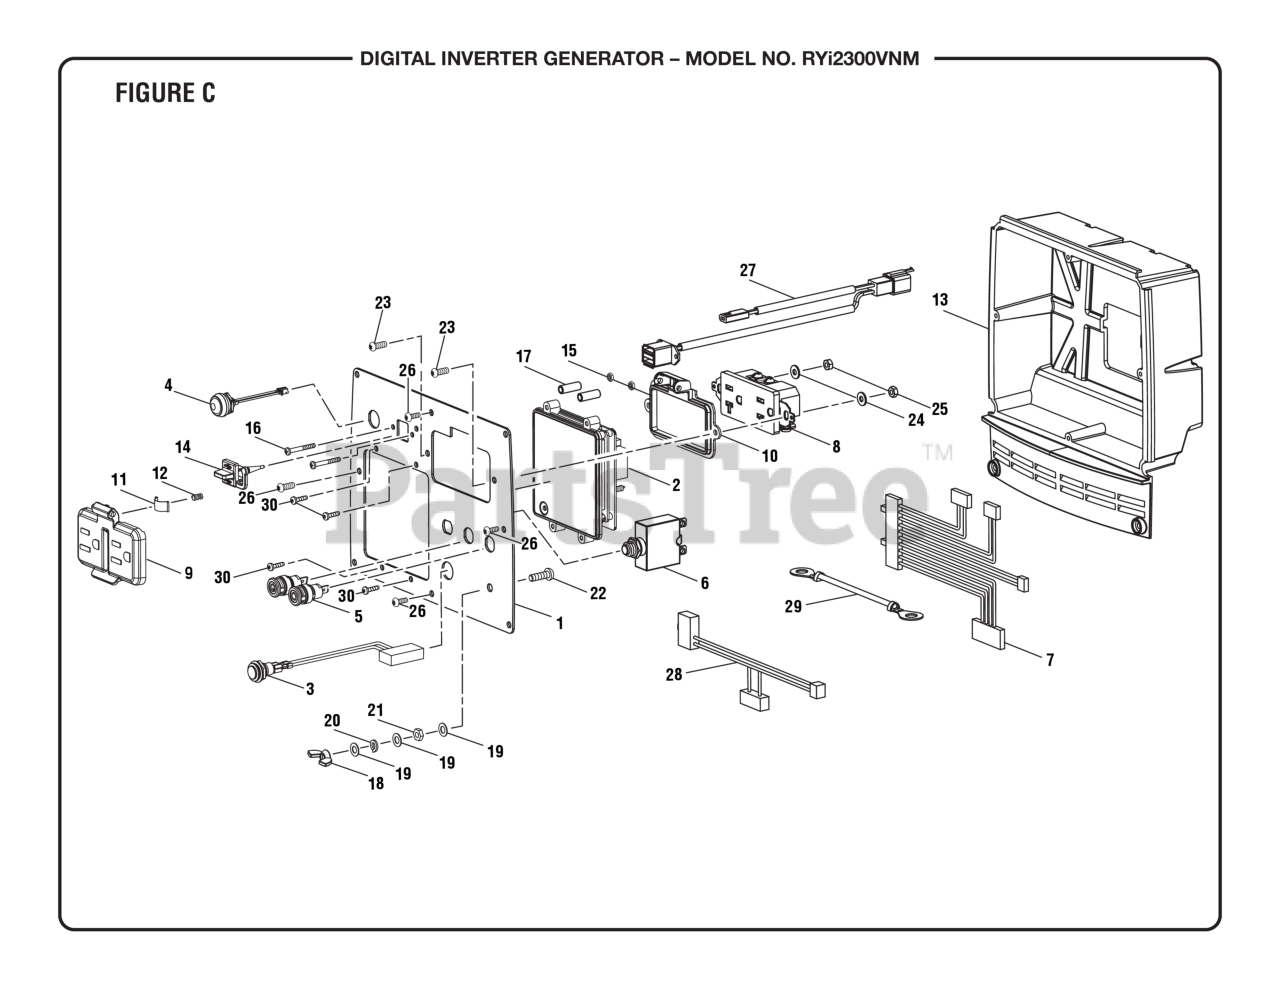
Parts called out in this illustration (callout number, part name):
1	Faceplate
2	GEN CONTROL DISPLAY ASSEMBLY RYi2300BTA
3	Overload Reset Button
4	Auto Idle Button
5	Connector (Black)
6	Circuit Breaker (20 Amp, 125 Volt)
7	Wire Harness (GENControl(TM) Display)
8	120 Volt Duplex Receptacle (BM903611)
9	Receptacle Cover (Front)
10	Fixed Outlet Cover
12	Governor Damping Spring
13	Electrical Panel Housing
14	Dual USB Cover
15	Hex Nut (M3)
16	Screw (M3 x 25 mm, Phillips Pan Hd )
17	Spacer (17.2 mm)
18	Wing Nut (M5)
19	Flat Washer (OD10 x ID5.3 x 0.5t)
20	Lock Washer (OD9 x ID5 x 1.3t)
21	Hex Nut (M5)
22	Screw (M5 x 16 mm, Phillips Pan Hd.)
23	Bolt (M4 x 10 mm, T15 Torx Drive Hd.)
24	Flat Washer (OD10 x 42 x 1t)
25	Flange Nut (M4)
26	Screw (#6-20 x 3/8 in., T15 Torx Pan Hd.)
27	Regulator Wire Harness w/ USB Ports
28	Internal Wire Assembly
29	Ground Wire
30	Screw (M3.1 x 10 mm, Torx pan Hd.)
